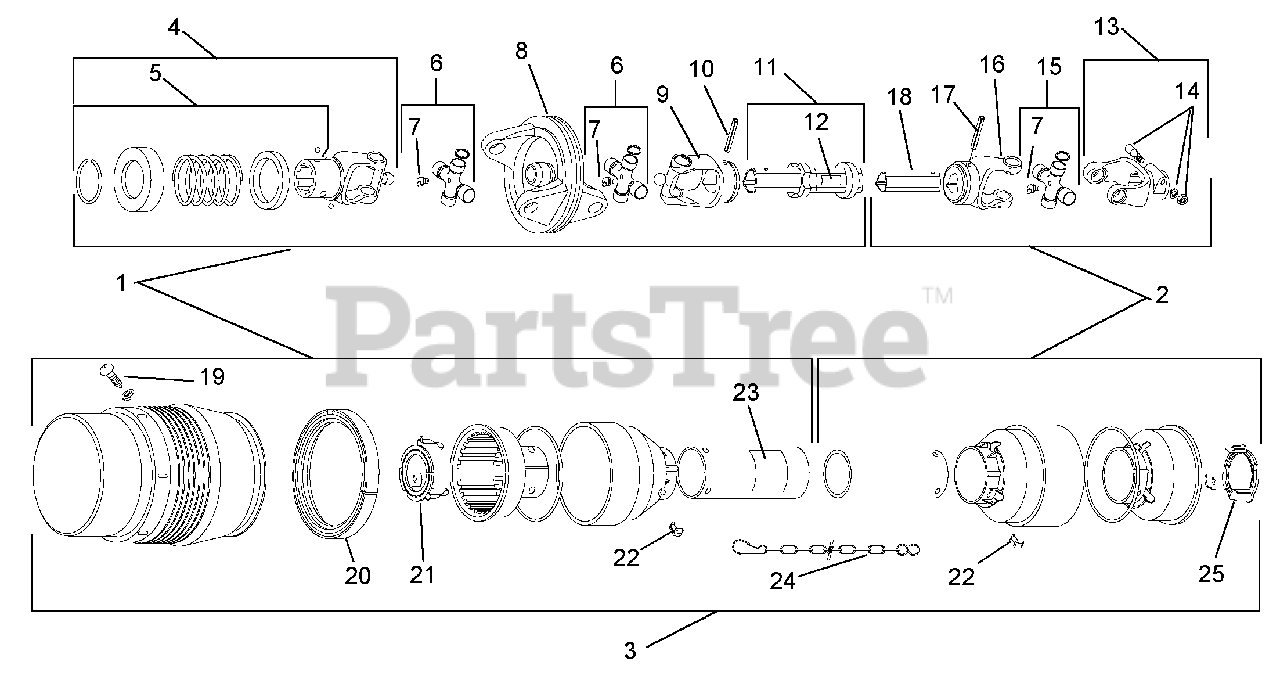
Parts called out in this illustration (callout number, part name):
1	Shaft Assembly, PTO Tractor Half
2	Shaft, Male Half With Shielding
3	Shield Assembly, Complete
4	Collar Yoke, Complete
5	Kit, Ball Collar 1.38
6	Cross Journal, Set
7	Fitting, Grease 45-Degree 8 mm x 1 mm x .88-In.
8	Yoke, Wide Double Angle
9	Yoke, Outer
10	Roll Pin, Outer Tube
11	Outer Tube, Complete
12	Decal, Danger
13	Yoke, Complete
14	Set, Tapered Pin 1.38
15	Kit, Cross and Bearing
16	Yoke, Inner Tube
17	Roll Pin, Inner Tube
18	Tube, Inner
19	Kit, Screw and Washer
20	Ring, Bearing
21	Guard, Retaining Collar
22	Fastener, Shield
23	Decal, Danger
24	Chain, Safety
25	Guard, Retaining Collar
